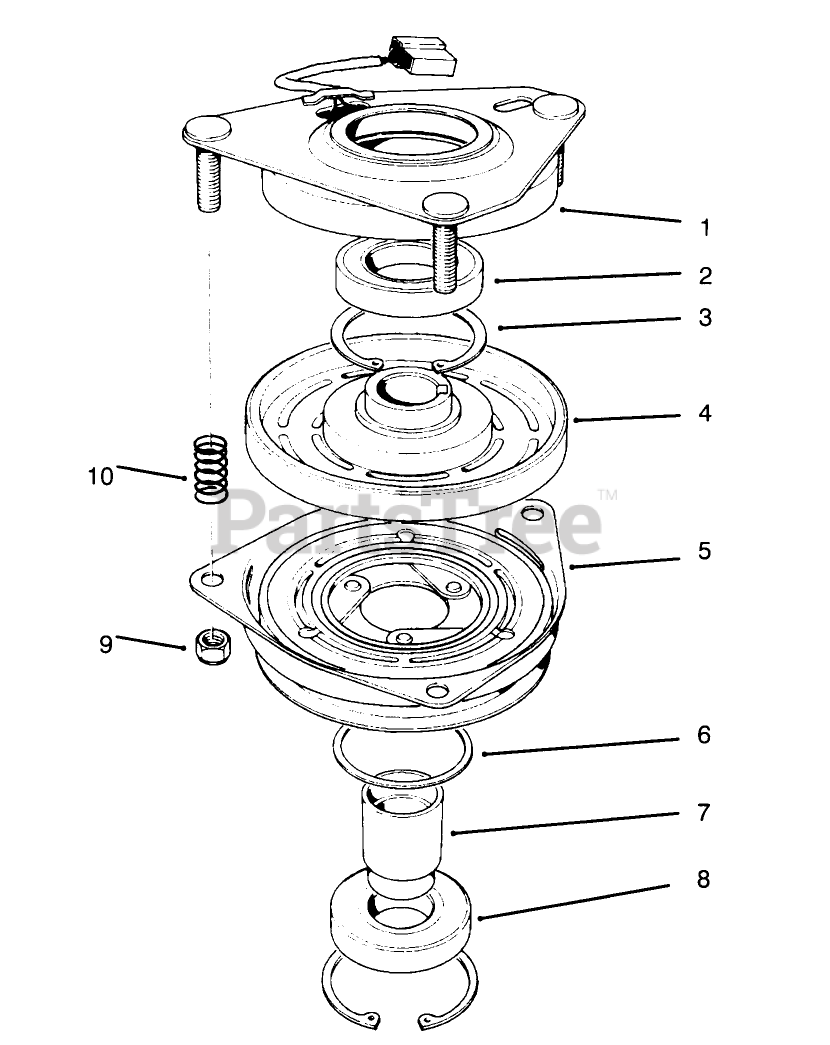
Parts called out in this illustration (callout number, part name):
1	FIELD BEARING ASM
2	BEARING-FIELD
3	RING-RETAINING
4	Field Coil, Rotor Bearing(Incl Ref. #1)
5	Armature Pulley Assembly(Incl Ref. #3, 6, 7, 8)
6	SPACER-BEARING, PULLEY
7	COLLAR-BEARING
9	NUT-LOCK
10	SPRING
